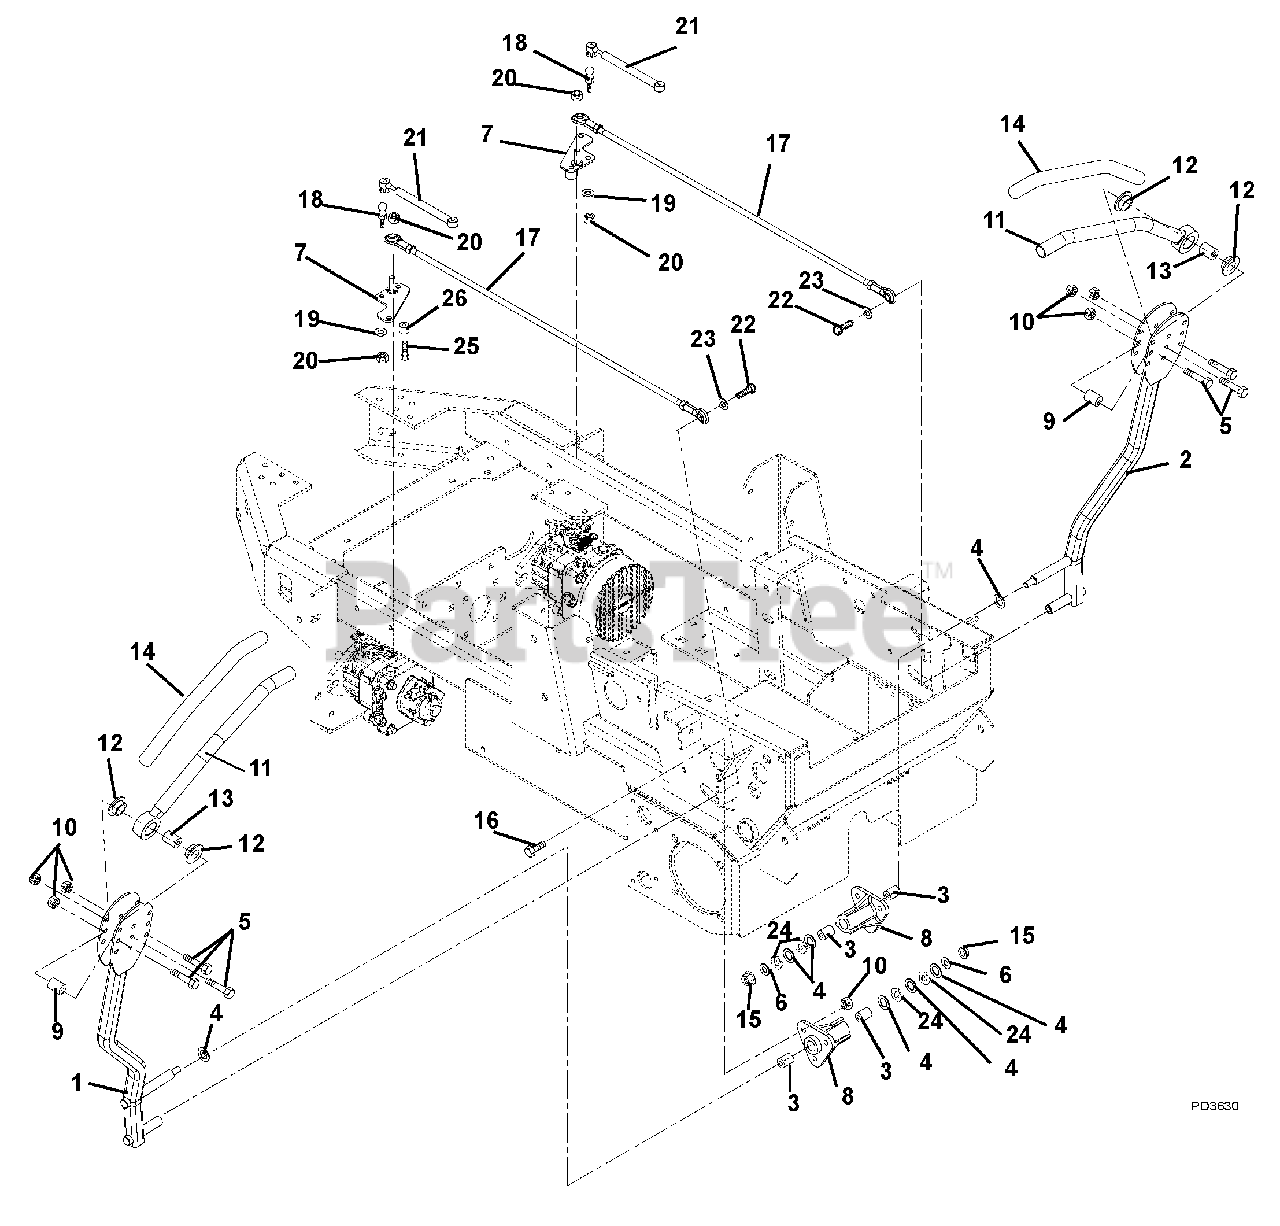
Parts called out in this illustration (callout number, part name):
1	Weldment, Bent Steering Arm-Right Hand
2	Weldment, Bent Steering Arm-Left Hand
3	Bushing .625 x .75 x .50
4	Washer-Flat-Steel .630 x 1.005 x .062
5	Bolt, Hex .31-18 x 1.75 Grade 5
6	Washer, Flat Steel .438 x 1.00 x .083
7	Weldment, Damper, Steering
8	Housing, Bushing
9	Eccentric
10	Nut, Nyloc Flange .31-18
11	Handle, Left Hand
12	Bushing, Flange Nylon .762 x 1.48 x .44
14	Grip, Handlebar
15	Nut, .38-16 Nyloc Flange
16	Bolt, Round Head Square Neck .31-18 x 1.00 Grade 5
17	Assembly, Steering Rod .38ROD x 30.43LG
18	Stud, Ball
19	Washer, Locking .31 x .078 Regular
20	Nut, .31-18 Nyloc Flange
21	Damper, Control
22	Bolt, Hex .38-16 x 1.00 EP30
23	Washer, Flat-Steel .406 x .812 x .065
24	Wave Washer .640 x .875 x .125
25	Bolt, Hex .31-18 x 1.25 Grade 5
26	Spacer .318 x .430 x .375
